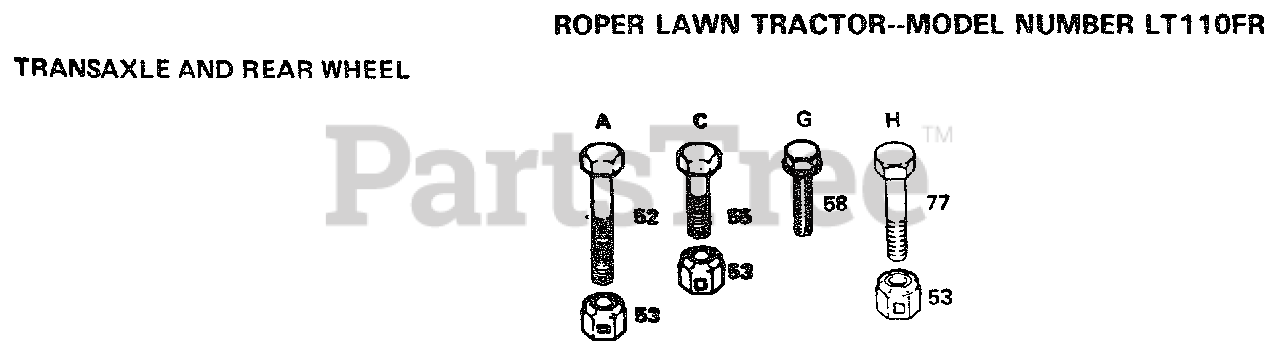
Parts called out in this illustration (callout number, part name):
52	BOLT
58	SCREW
77	BOLT
